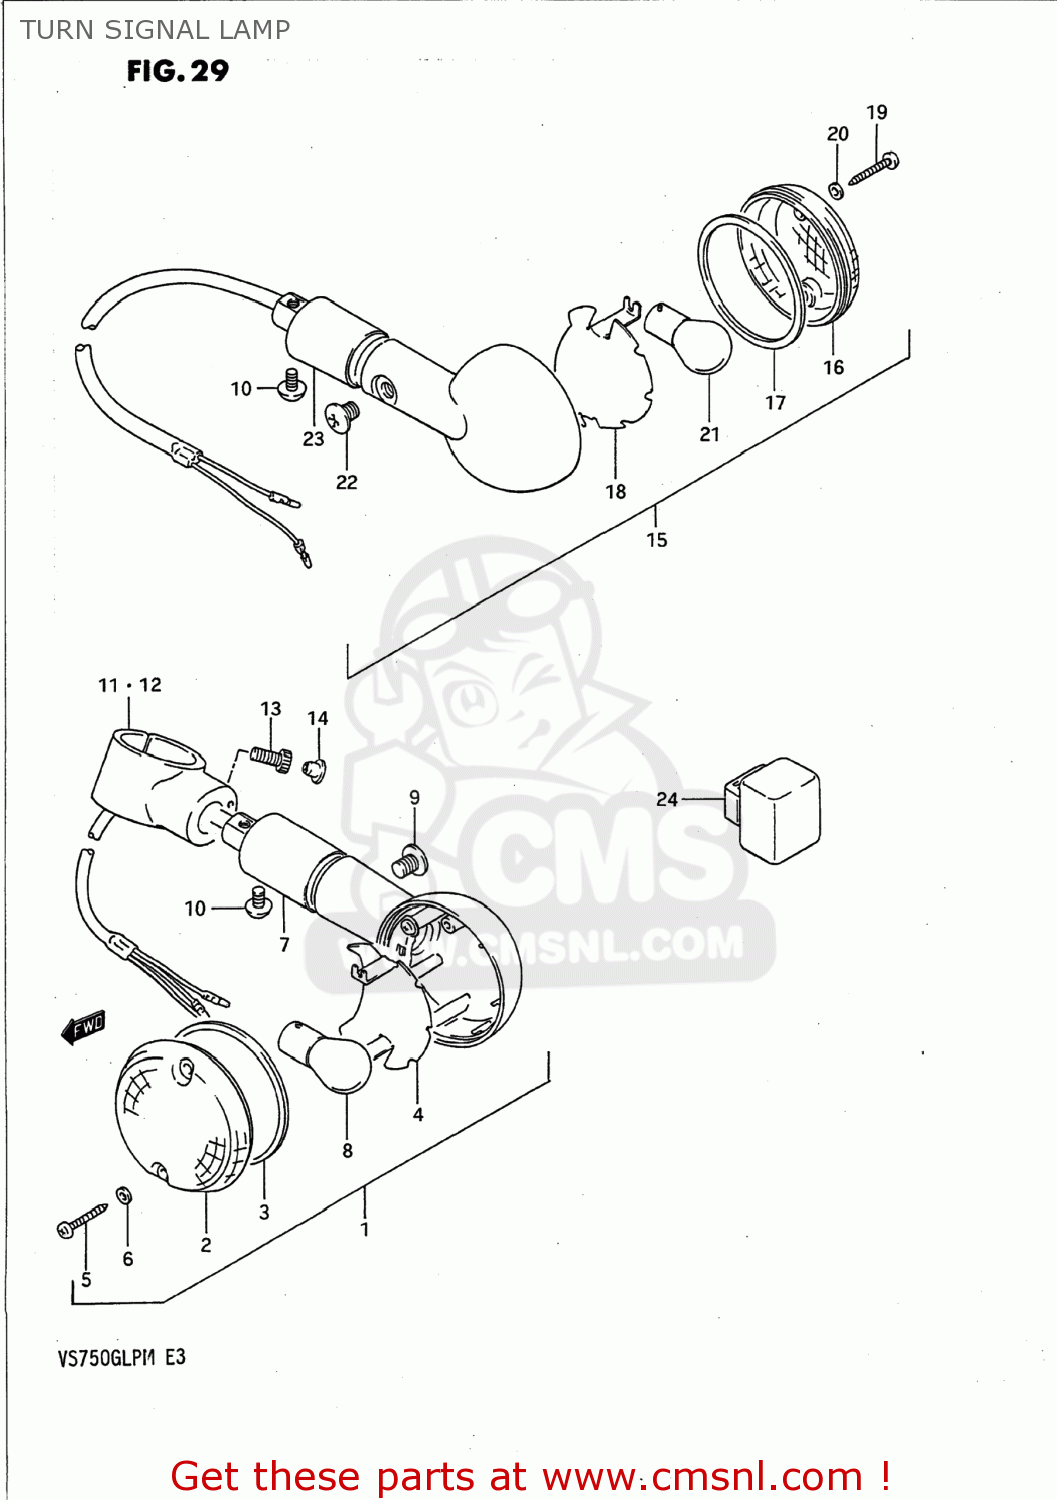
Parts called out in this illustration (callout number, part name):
1	LAMP ASSEMBLY,FRONT TURN SIGNAL
2	LENS
3	GASKET (NAS)
4	REFRECTOR
5	SCREW ,4X25
6	GASKET (NAS)
7	STAY,TURNSIGNAL LAMP
8	BULB(12V21/5W,BF141-49642A)
9	SCREW
10	SCREW
11	BRACKET,FR TURNSIGNAL LAMP,R
12	BRACKET,FR TURNSIGNAL LAMP,L
13	BOLT
14	CAP(OD:10)
15	LAMP ASSEMBLY,REAR TURN SIGNAL
16	LENS
17	GASKET (NAS)
18	REFRECTOR
19	SCREW ,4X25
20	GASKET (NAS)
21	BULB 12V 21W
22	SCREW
23	STAY,TURNSIGNAL LAMP
24	RELAY ASSEMBLY,TURN SIGNAL
